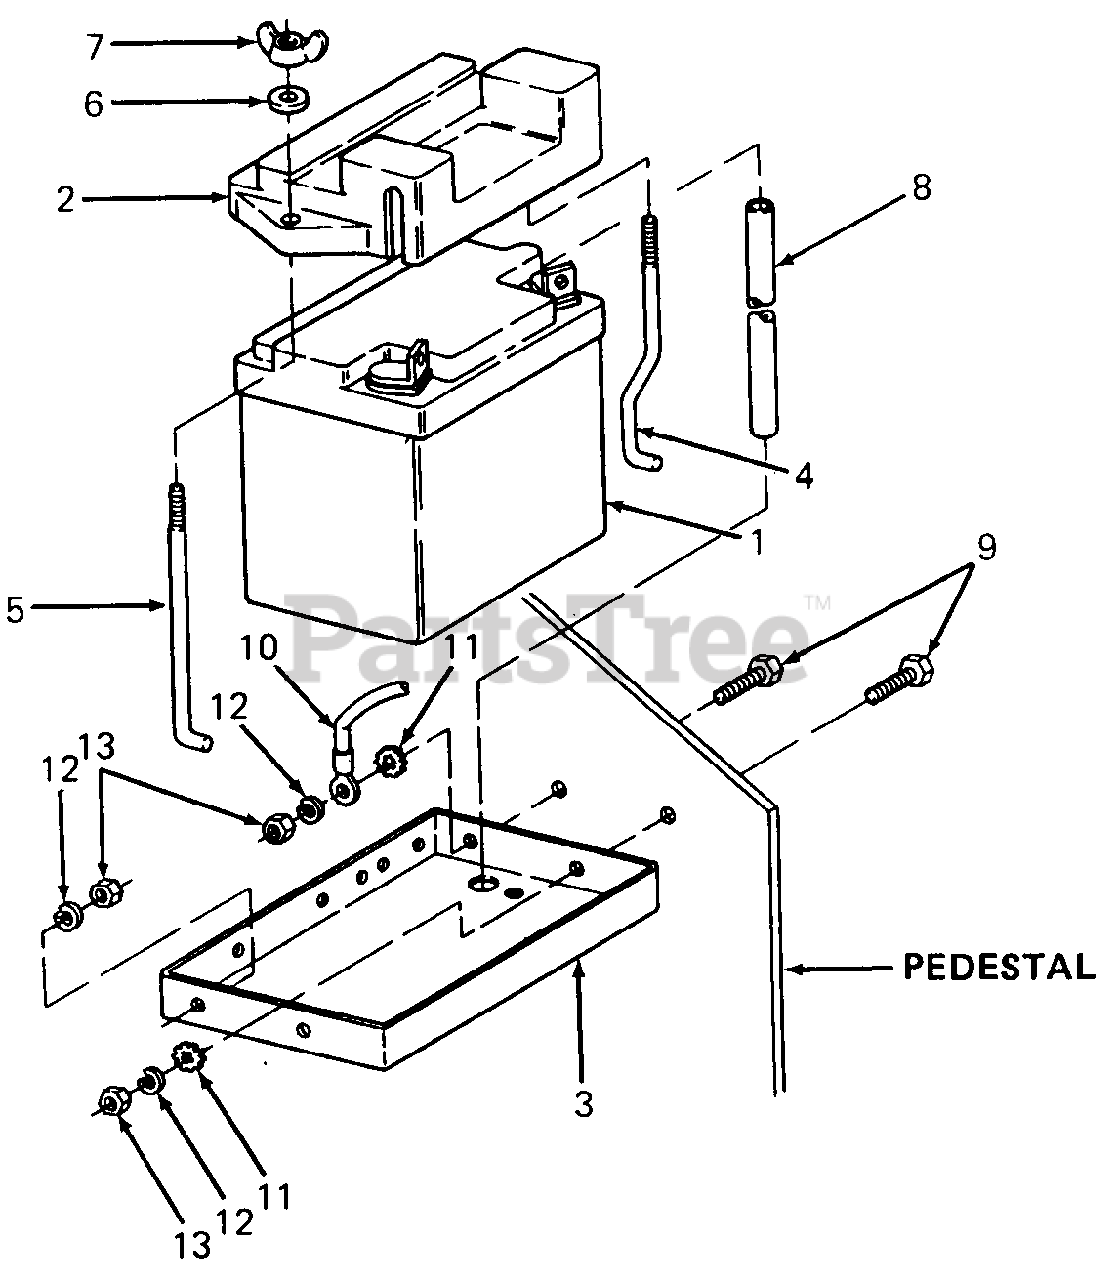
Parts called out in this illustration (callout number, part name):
1	Battery, 12 Volt
2	Cover w/Graphic, Battery
3	Tray, Battery
4	Rod, Battery Cover, LH
5	Rod, Battery Cover, RH
6	Washer, Flat, .281 X .500 X .056
7	Nut, Wing, 1/4-20
8	Hose, Battery Drain, 48 in. Lg
9	Screw, Hex Cap, 5/16-18 X .75 Lg GR5
10	Wire, Ground, 9.0 Lg
11	Washer, Int. Ext. Lock, 5/16 ID X .875 OD
12	Washer, Lock, 5/16
13	Nut, Hex, 5/16-18
